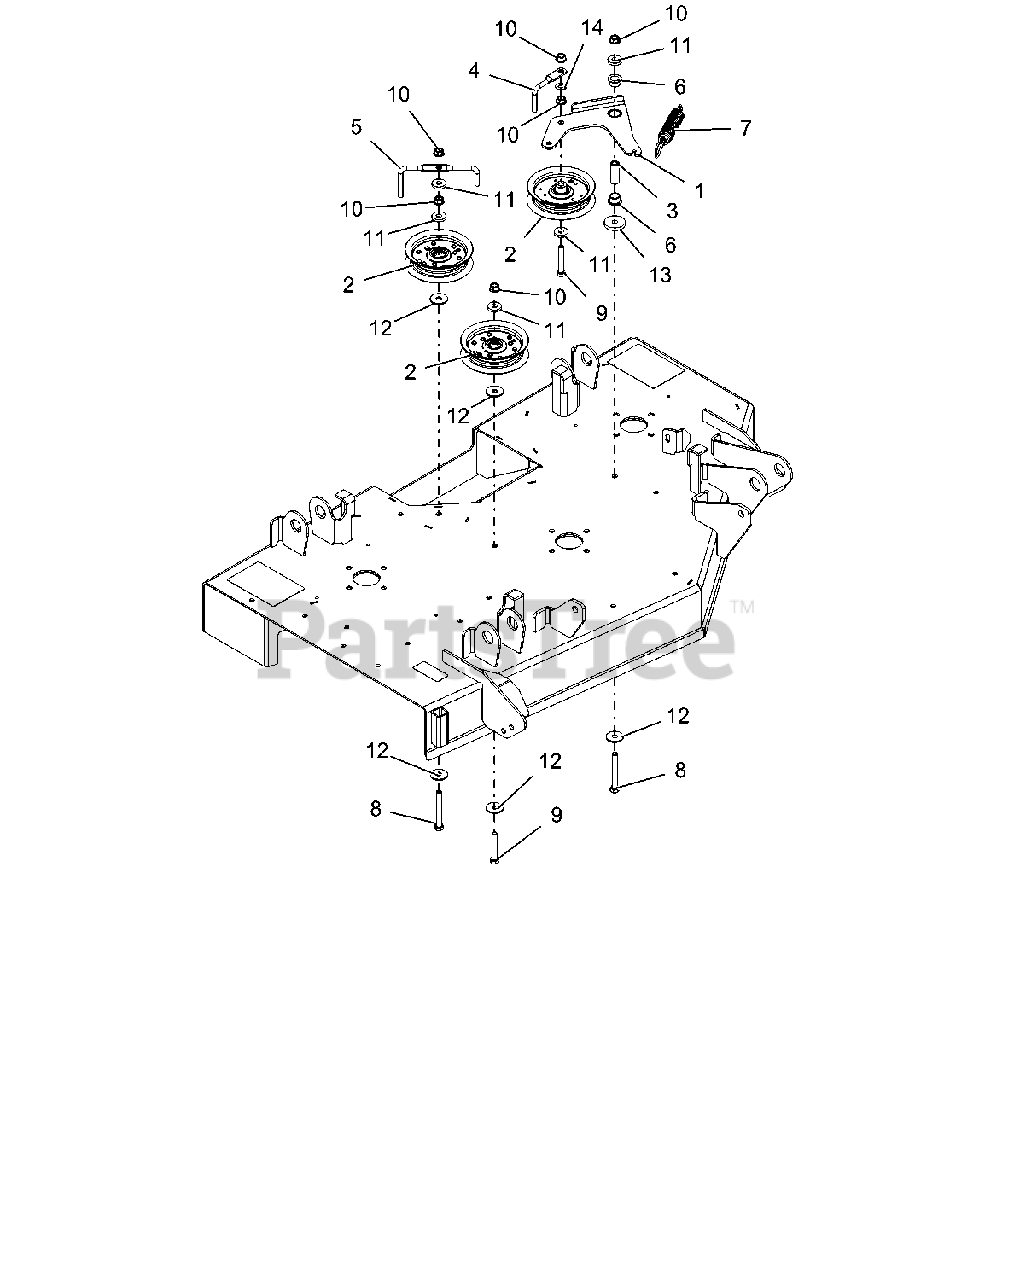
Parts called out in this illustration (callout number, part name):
1	WLDMT, IDLER ARM-42"
2	ASM, IDLER 4"
3	SPACER, .375IDX.625ODX1.66 PM
4	WIREFORM, BELT FINGER
5	WIREFORM, BELT FINGER
6	BSHG-FLG, .625X.750X.500X1.00
7	SG-TENS .135X.98X6.0 WLD 62
8	BLT-HEX .38-16X3.00 GR5 FTH YZ
9	@BLT-HEX .38-16X2.25 GR5 YWZC
10	@NUT-LK-TOP-FLG .38-16 YWZC
11	WSHR-FL-STL .406X1.00X.188 YWZ
12	@WSHR-FL-STL .406X1.25X.10 ZC
13	WSHR,FLT STL.406X1.50X.245YWZC
14	@WSHR-FL-STL.406X.812X.065 YWZ
